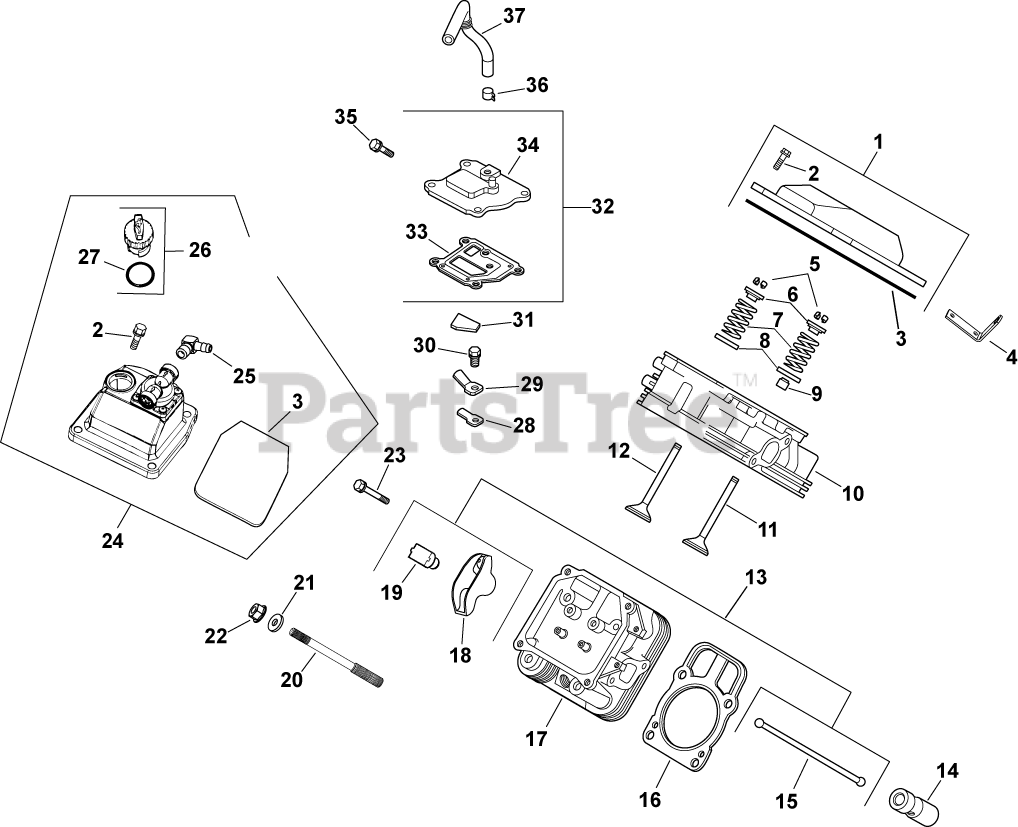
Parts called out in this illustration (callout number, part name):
1	KIT, VALVE COVER-PLAIN
2	SCREW, FLG M6X1.0X30
3	O-RING (YELLOW) -USE 24 153 30-S
4	STRAP, LIFTING-USE 25 445 03-S
5	KIT, RETAINER
6	RETAINER, VALVE SPRING - USE 25 173 28-S
7	SPRING, VALVE
8	RETAINER, SPRING
9	SEAL, VALVE STEM - (#2503214S)
10	HEAD, ASSEM CYLINDER #1 -USE 24 318 107-
11	VALVE, INTAKE (STD)
12	VALVE, EXHAUST (STD) - USE 32 016 01-S
13	KIT, VALVE TRAIN
14	LIFTER, HYDRAULIC VALVE-USE 25 351 10-S
15	ROD, PUSH
16	KIT, GSKT CYL HD (C22-23 674CC)
17	HEAD, ASSEM CYLINDER #2 -USE 24 318 115-
18	ARM, ROCKER
19	PIVOT, ROCKER ARM
20	STUD, M8X1.25
21	WASHER, FLAT 8.6 MM
22	NUT, FLG M8X1.25
23	SCREW, ROCKER ARM PIVOT-USE M-640034-S
24	KIT, VALVE COVER-FUEL PUMP
25	KIT, 90 DEG. FITTING
26	CAP ASSY, OIL FILL (YELLOW)
27	O-RING-USE 24 153 32-S
28	REED, BREATHER
29	RETAINER, REED
30	SCREW, FLG THD FRM M5X.8X10
31	FILTER, BREATHER-USE 24 050 11-S
32	KIT, BREATHER ASSEMBLY
33	GASKET, BREATHER-USE 24 041 67-S
34	COVER, BREATHER -USE 24 033 01-S
35	SCREW,FLG THD FRM M6X1.0X20-(#25086396S)
36	CLAMP, HOSE (KM)-USE 25 237 31-S
37	HOSE, BREATHER-USE 24 326 89-S
2401602-S	VALVE, EXHAUST (.25)
2401702-S	VALVE, INTAKE (.25)
